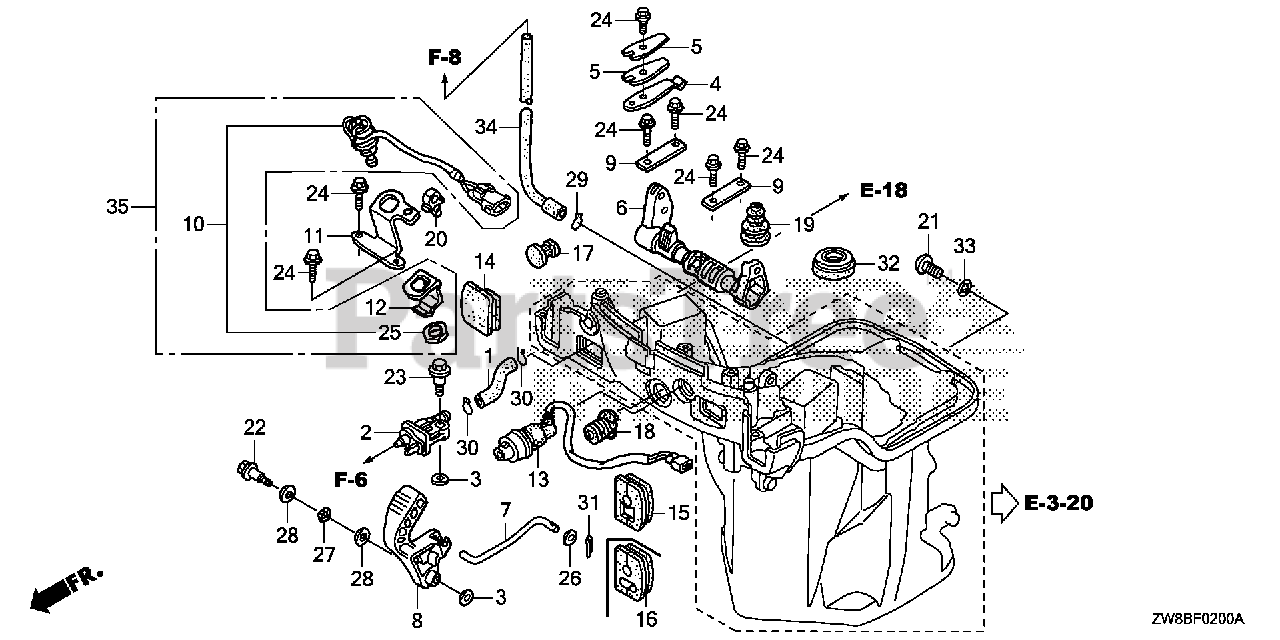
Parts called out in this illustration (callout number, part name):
1	TUBE A, FUEL
1	TUBE A, FUEL (FKM)
2	CONNECTOR ASSY., FUEL (B)
3	WASHER, PIVOT
4	SPRING, CLICK
5	SPRING, CLICK ASSIST
6	SHAFT, SHIFT
8	LEVER, SHIFT
9	PLATE, SHIFT SHAFT
11	BRACKET, NEUTRAL SWITCH
13	LAMP ASSY., INDICATOR
14	GROMMET A, OIL CASE
16	GROMMET B, OIL CASE
17	GROMMET F, OIL CASE
18	GROMMET D, OIL CASE
19	GROMMET E, OIL CASE
20	CLIP, BRAKE PIPE (A)
21	BOLT, OIL CHECK
22	BOLT, REVERSE LOCK
23	BOLT, SPECIAL (6X22) (CT200)
24	BOLT, FLANGE (5X12) (CT200)
25	NUT, HEX. (20MM)
26	WASHER, PLAIN (5MM)
27	WASHER, WAVE (10MM)
28	WASHER, PLAIN (9MM)
29	CLIP, TUBE (B10)
30	CLIP, TUBE
30	CLIP, TUBE (B12)
31	PIN, SPLIT (2.0)
32	SEAL, WATER (13X28X7) (ENGINE NO.)
33	O-RING (5.5X1.5)
34	TUBE, WATER CHECK
35	SWITCH SET, NEUTRAL
